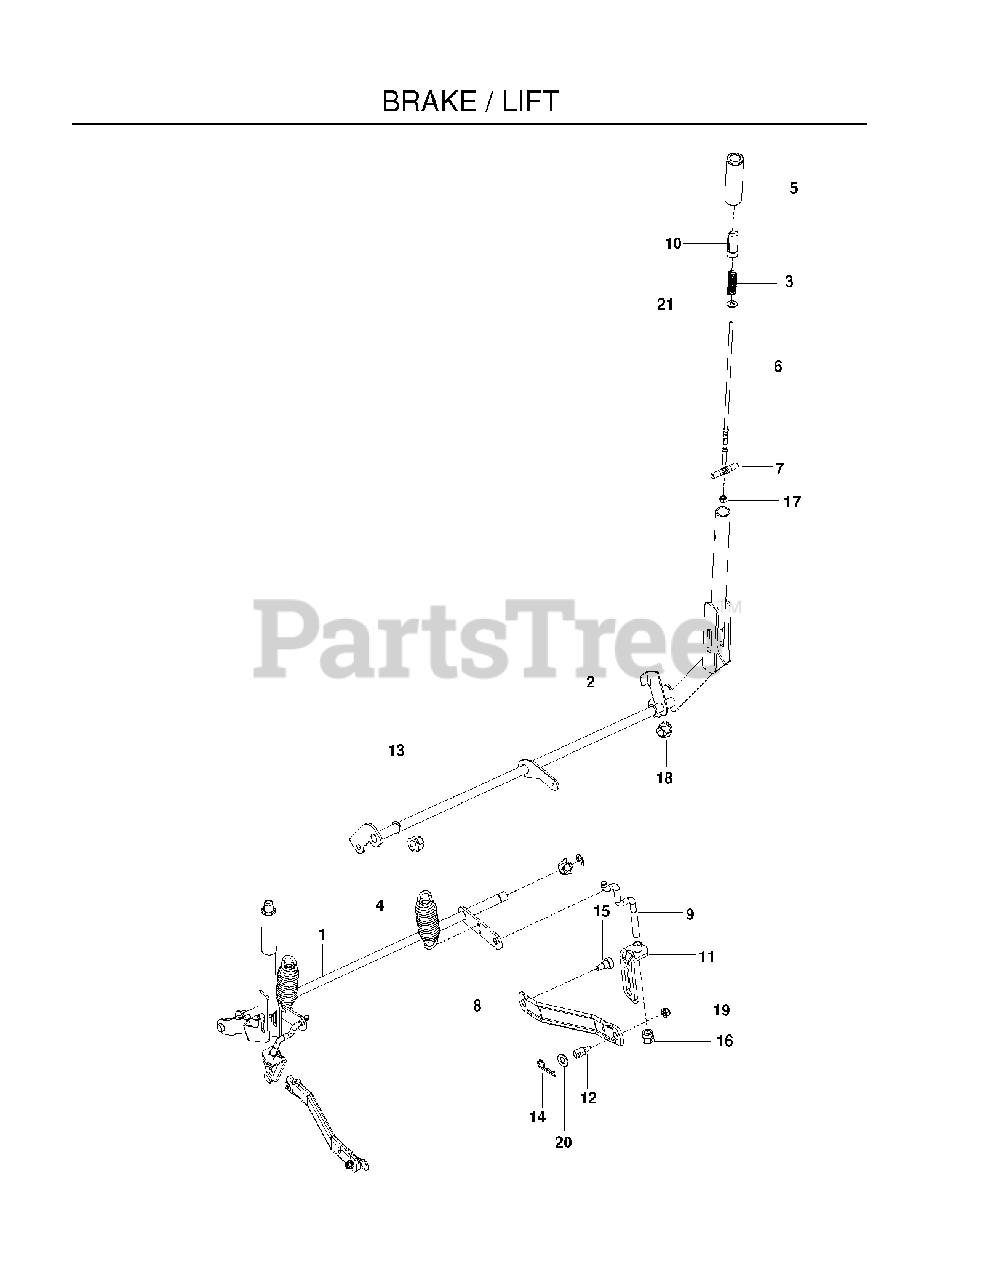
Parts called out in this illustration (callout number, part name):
1	SHAFT.LIFT.MED.BLACK
2	SHAFT ASSY, BRAKE, MED, BLK
3	SPRING, COMPRESSION
4	SPRING
5	GRIP, HANDLE, BLACK
6	ROD, HANDLE RELEASE
7	ROD, LATCH RELEASE
8	ARM.SUSPENSION.MOWER
9	LINK, REAR SUSPENSION
10	BUTTON, PUSH, BLACK (2 2)
11	ASSEMBLY, BRKT LINK
12	STUD.FASTNER.W/ANTI-ROTATE
13	E-RING 5/8
14	HAIRPIN #4
15	SB 3/8-16 X 3/8 SKT HD ZD
16	NUT, LIFT LINK 7/16-20
17	NUT 1/4-20 NYLOC
18	PLASTIC NUT
19	5/16-18 NYLOC FLANGE NUT
20	WASHER 5/8 FLAT
21	WASHER 1/4 FLAT
